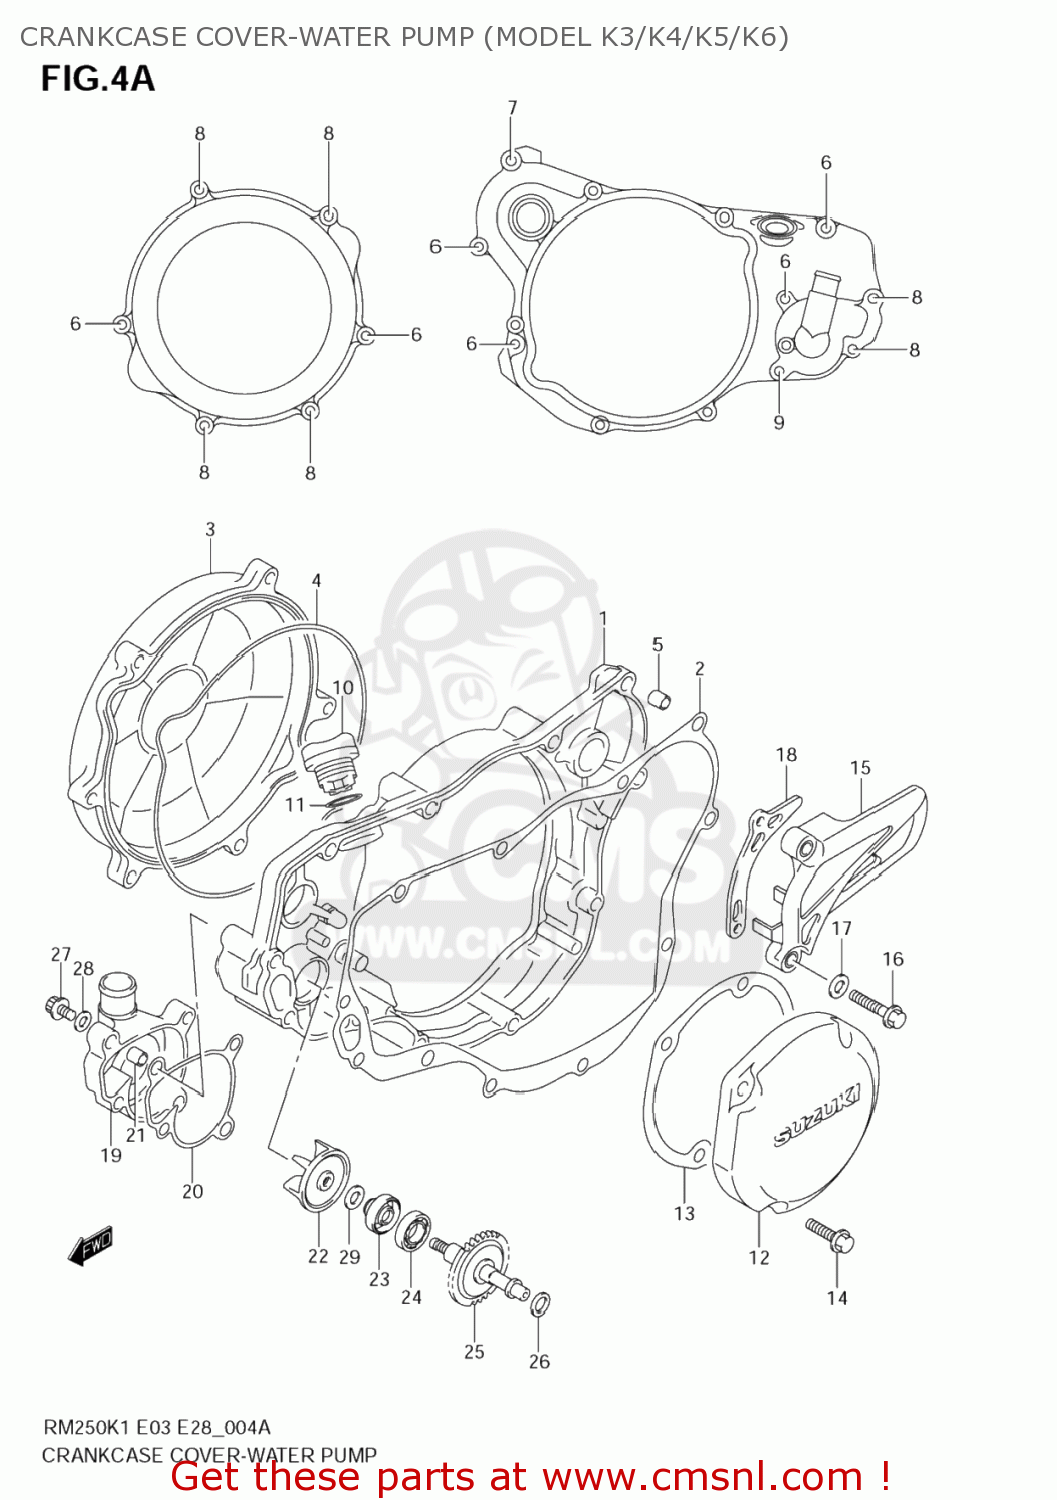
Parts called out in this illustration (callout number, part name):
1	COVER,CLUTCH
2	GASKET,COVER (NAS)
3	COVER,CLUTCH OUTER
4	O RING,CL COVER OUTER
5	PIN
6	BOLT(6X25)
7	BOLT(6X30)
8	BOLT(6X60)
9	BOLT(6X65)
10	PLUG,OIL FILLER
11	O RING(D:3.1,ID:16.8)
12	COVER,MAGNETO
13	GASKET,MAGNETO COVER
14	BOLT,6X20
15	COVER,ENGINE SPROCKET
16	BOLT(6X30)
17	WASHER
18	PLATE,FR CHAIN GUIDE
19	CASE,WATER PUMP
20	GASKET,WATER PUMP CASE (NAS)
21	PIN
22	IMPELLER,WATER PUMP
23	SEAL,WATER PUMP OIL
24	BEARING
25	SHAFT,WATER PUMP
26	SHIM(8.8X14X1)
27	BOLT
28	GASKET(6.2X11X1).2 (NAS)
29	WASHER
